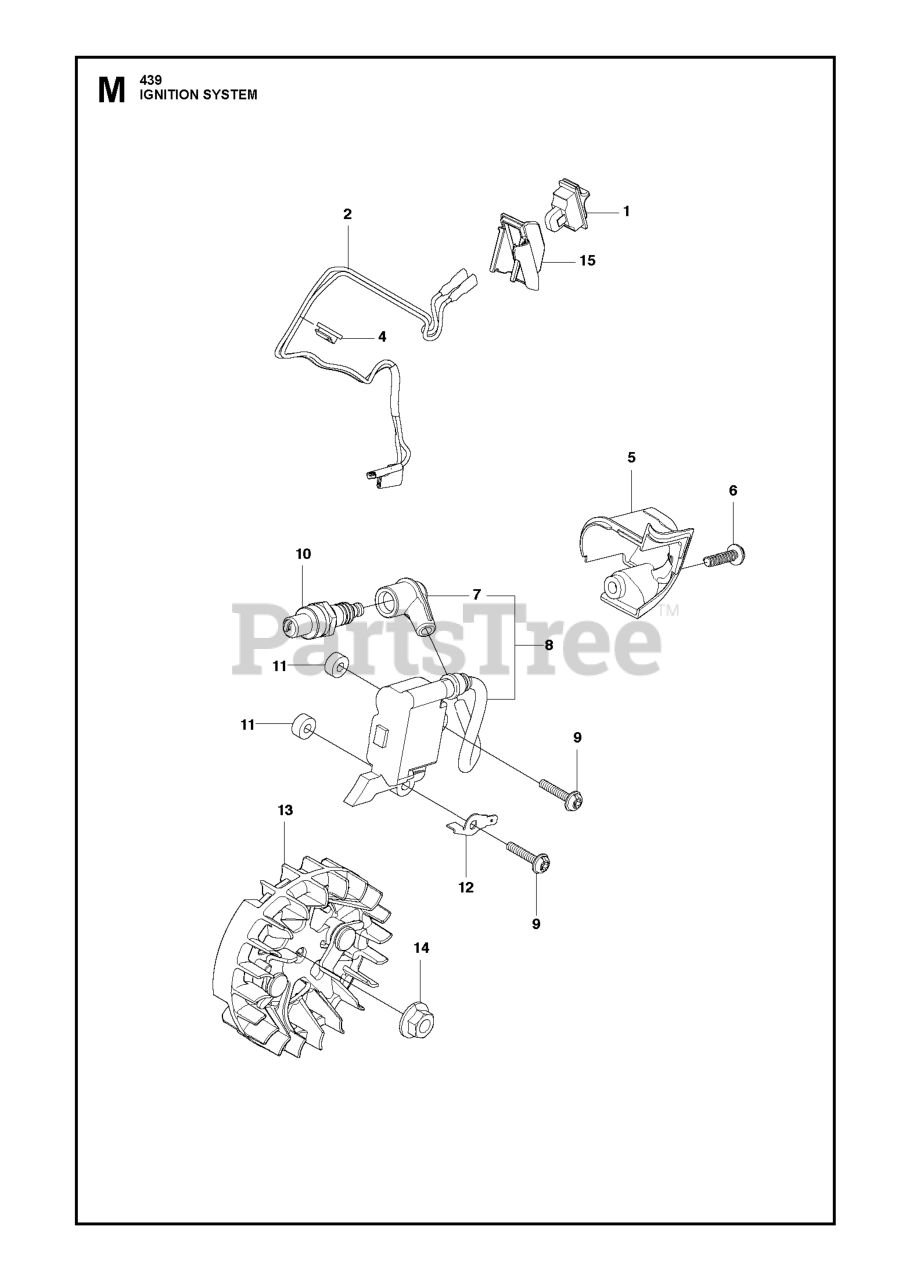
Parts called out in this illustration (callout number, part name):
1	STOP SWITCH OPS ROTATE "STOP"M
2	WIRING ASSY
5	COVER SPARK PLUG GRAY
8	IGNITION COIL ASSY
9	BOLT M4X20
10	SPARK PLUG (CMR6H)
13	FLYWHEEL ASSY
14	NUT
15	BRACKET SWITCH 439
